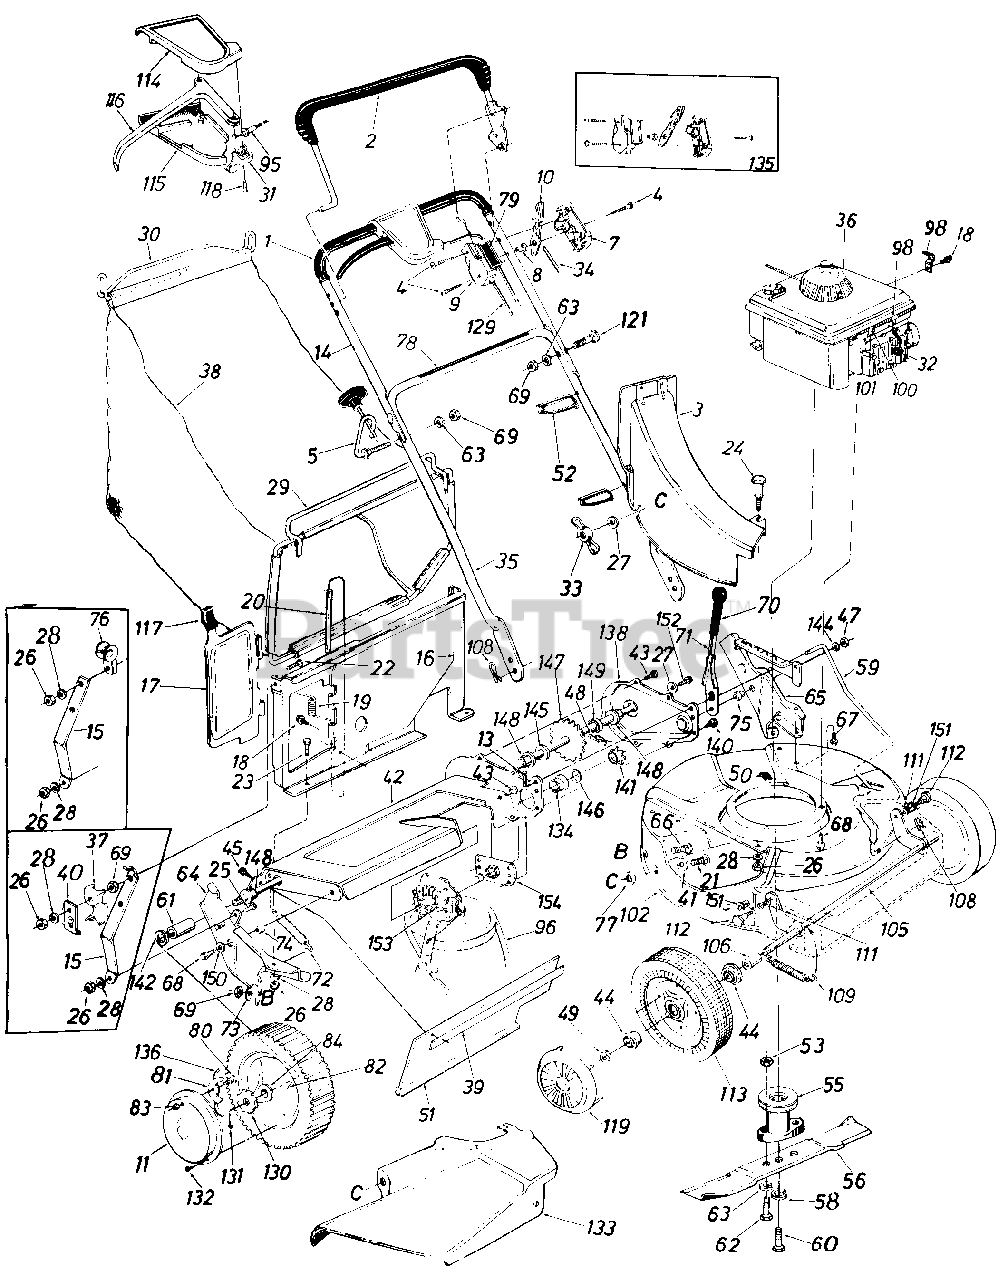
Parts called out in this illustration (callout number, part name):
1	Grip
2	Control Handle Ass'y. L.H.
3	Top Discharge Chute Ass'y.
4	Truss Mach. Scr. #12 x 1.50" Lg.
5	Rope Guide Bolt
7	Control Panel Half
8	Control Disc Pin
9	Clutch Panel Half
10	Throttle Control Lever
11	Hub Cap
13	Cotter Pin 3/32" Dia. x .75"
14	Upper Handle Chrome
15	Panel Support Brkt.
16	Top Catcher Panel
17	Top Door
18	Hex B-Tap Scr. #10 x .38"
19	Torsion Spring
21	Carriage Bolt 1/4-20 x .62"
22	Truss Mach. Scr. 1/4-20 x 3/4 " Lg
23	Hex Bolt 1/4-20 x .50" Lg.
24	Shoulder Bolt .312 Dia. x .18 Lg. Special
25	Hex Bolt 1/4-20 x .62" Lg.
26	Hex Nut 1/4-20 Thd.
27	Bell-Wash. 1/4" I.D.
28	L-Wash. 1/4" I.D.*
29	Front Grass Catcher Frame
30	Grass Catcher Handle
31	S.P. Control Cover
32	Spark Plug Insulator
34	Throttle Control Wire 58"
35	Lower Handle Chrome
36	Engine
37	Rope Guide Half
38	21" Top Discharge Grass Bag
39	Retaining Strip
40	Rope Retainer Spring Clip
41	Fl-Wash. .344" I.D. x .62"
42	Chain Axle Ass'y.
43	Hex B-Tap Scr. 1/4" x .38" Lg.
44	Flange Ball Bearing 1/2" I.D.
45	Hex AB-Tap Scr. 1/4 x .62"
47	Hex Patch L-Nut 3/8-24 Thd.
48	#48 Chain .500" Pitch x .30 0 Links
49	Hex L-Nut 1/2-20 Thd.
51	Rear Flap 3.75" x 17.30" Lg.
52	Cable Tie
53	Hex Nut 5/16-24 Thd.
55	Blade Adapter w/Pulley
56	21" Blade
58	Bell-Wash. .39" I.D. x 1.380" O.D.
59	Height Adj. Rod 19.42" Lg.
60	Hex Bolt 3/8-24 x 2.25" Lg. (Grade 5)
61	Spacer .513" I.D. x .703" O.D. x .69" Lg.
62	Hex Bolt 5/16-24 x 1.00" Lg. (Grade 5)
63	L-Wash. 5116 I.D.
64	R.H. Handle Wheel Brkt. Ass'y.
65	L.H. Handle Wheel Brkt. Ass'y.
66	Carriage Bolt 5/16-18 x .62
67	Hex Wash. Hd. B-Tap Scr. 5/1 6-1 8
68	Hex Wash. Hd. TT-Tap Scr. 3/8-1 6
69	Hex Nut 5/16-18 Thd.
71	Height Adj. Lever
72	Extension Spring .50" O.D. x 3.80" Lg.
73	Bell-Wash. 5116" I.D.
74	Spacer .385" I.D. x .502" O.D. x .270" Lg.
75	Shld. Spacer .500" Dia. x .100
77	Bolt Retainer 1/4 X .50" O.D.
78	Instruction Label
79	Control Label
80	Shld. Scr. .342" Dia. x .268
81	Pawl
82	Wheel Ass'y. Comp. Rear 8 x 1 .75
83	Hex Ins. L-Nut 1/4-20 Thd.
84	Flange Ball Bearing 1/2" I.D.
95	S.P. Cable x 50" Lg.
96	"V"-Belt
98	Casing Clamp
100	Hex B-Tap Scr. #10 x .62"
101	Casing Clamp
106	Sleeve .526" I.D. x .690" O.D. x .880" Lg.
108	Intern. Cotter Pin 5/16" Dia.
109	Extension Spring .50" O.D. x 3.20" Lg.
111	Intern. L-Wash. 3/8 I.D.
112	Shld. Bolt .623" Dia. x .425
113	Front-Wheel Ass'y. Comp. 7x 1.50
114	Self-Propelled Control Cover
115	Self-Propelled Control Cover
116	Control Lever
118	Fl-"C"-Sunk Hd. Tap Scr. #10 x .75" Lg.
119	Hub Cap Plastic
121	Curved Carr. Bolt 5/16-18 x 1.38" Lg.
129	Control Cable 43" Lg.
130	Ratchet Wheel 1.62" O.D.
131	Cotter Pin 1/8" Dia. x 1.00" Lg.
132	Pan Hd. Tap Scr. #12 x .50" Lg.
133	Side Chute Deflector Ass'y.
134	Flange Bearing
135	Kit Control Housing Comp.
136	Spring Nylon
138	Chain Cover
140	Hex Wash. S-Tap Scr. 1/4-20 x.50" Lg.
141	Sprocket Shaft Ass'y.
142	Fl-Wash. .510" I.D. x 1 on O.D.
144	Fl-Wash. .385" I.D. x .87" O.D.
145	Fl-Wash. .51" I.D. x 1.0" O.D.
146	Fl-Wash. 318" I.D.
147	Rear Shaft Ass'y. 21.94n Lg.
148	Hex Flange Bearing .506" I.D. Plastic
149	Fl-Wash. .531" I.D. x .930" O.D.
150	Fl-Wash. .631n l.D. x 1.25" O.D.
151	Flanged Nyliner Brg.
152	Hex Bolt 1/4-20 x .62" Lg. (Grade 5)
153	Transmission Comp.
154	Hex Bearing Cup
8182-000-7	Hardware Pack
